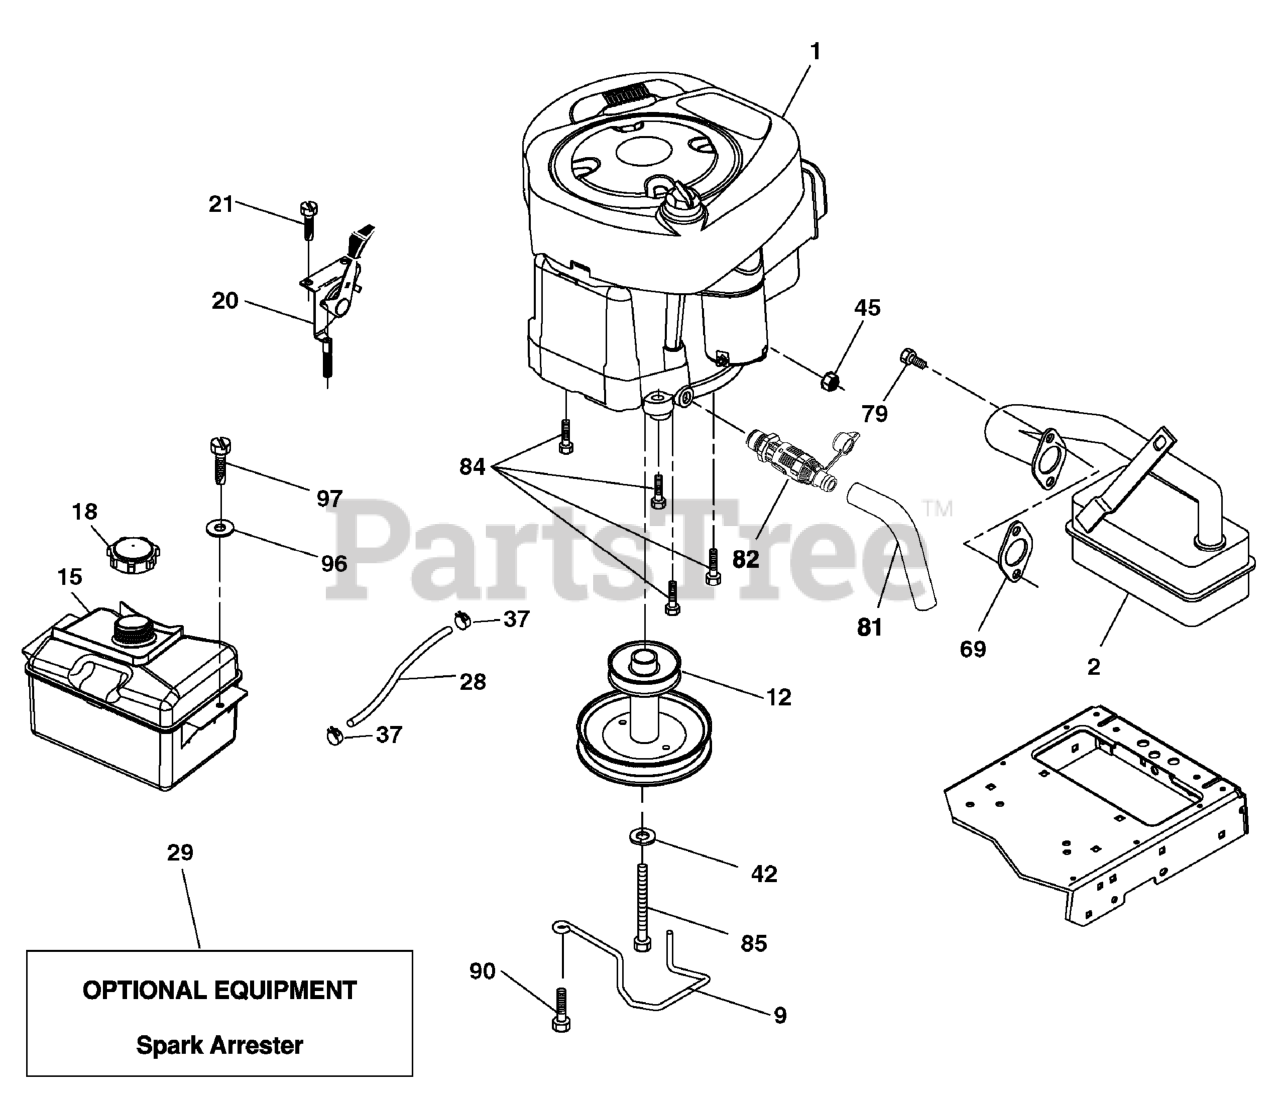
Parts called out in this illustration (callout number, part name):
1	Engine B&S
2	Muffler
9	Keeper Belt Engine
12	Pulley Engine
15	Tank Fuel 1.50
18	Cap Asm
20	Control Throttle/Choke
21	Screw #10 x 0.750
28	Fuel Line
29	Spark Arrester Kit
37	Clamp Hose
42	Washer Lock 7/16
45	Nut Keps Hex 1/4-20 unc
69	Gasket
79	Screw Socket Hd 5/16-18 x .75
81	Tube Drain Oil Easy
82	Valve Drain Oil
84	Screw 3/8-16 x 1-1/4
85	Bolt Hex 7/16-20 x 4 x Gr. 5-1.5
90	Screw 3/8-16 x 1.0
96	Washer 9/32 x 7/8 x 16 Ga.
97	Screw 1/4-20 x 3/4
